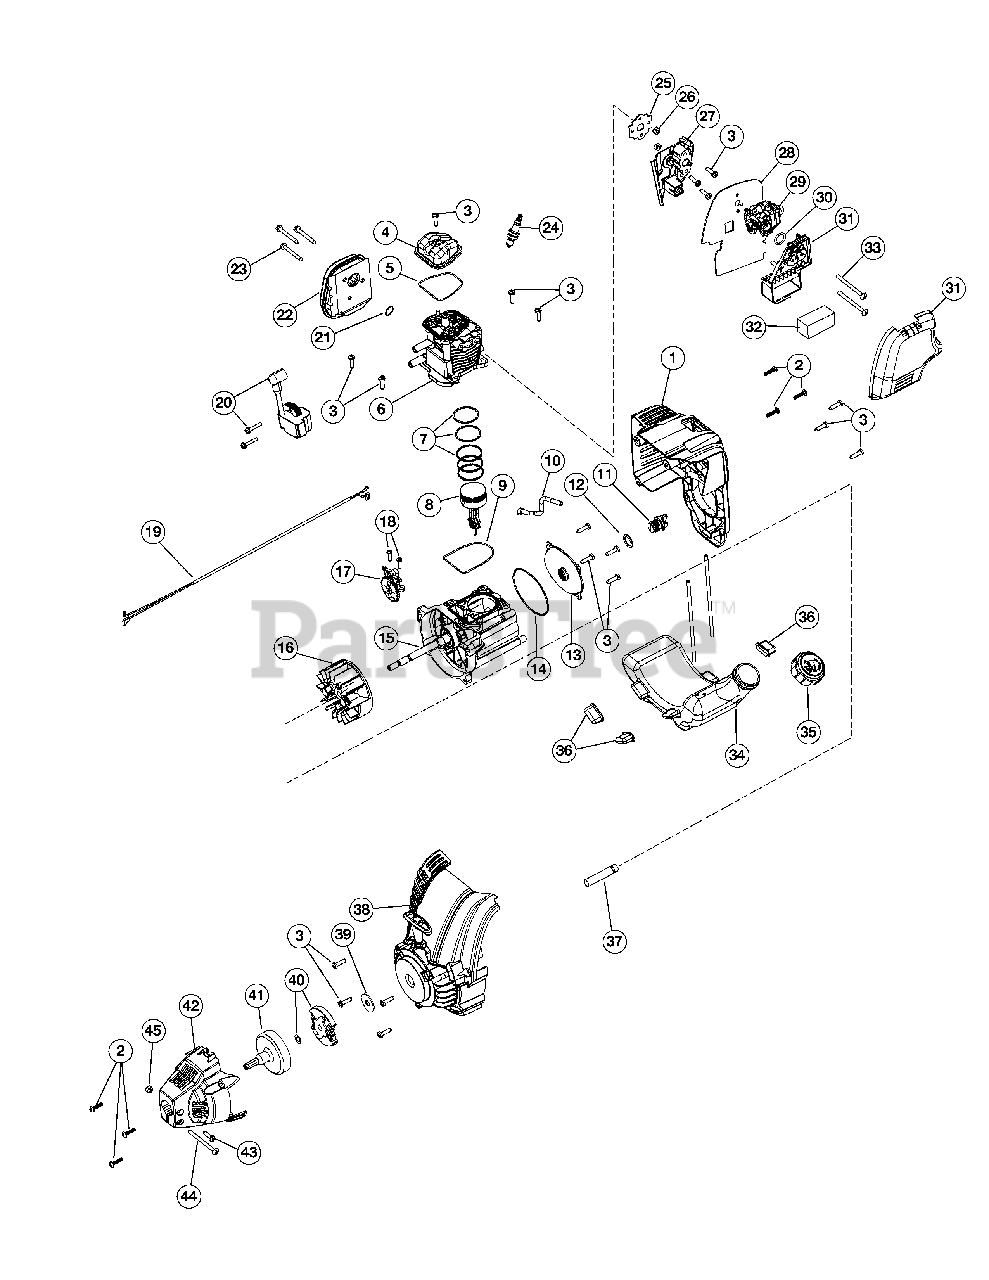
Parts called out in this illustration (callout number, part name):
1	Engine Cover Assembly
2	Cover Screw
3	Screw
4	Rocker Cover
5	Rocker Cover O-Ring
6	Cylinder Assembly
7	Piston Ring Assembly
8	Piston Assembly
9	Cylinder O-Ring
10	Breather Hose
11	Oil Plug
12	Oil Plug O-Ring
13	Crankcase Cover
14	Crankcase Cover O-ring
15	Crankcase Assembly
16	Flywheel Assembly
17	Cam Bracket Assembly
18	Cam Bracket Screw
19	Lead Wires
20	Module Assembly
21	Muffler Gasket
22	Muffler Assembly
23	Muffler Screw
24	Spark Plug
25	Insulator Gasket
26	Nut
27	Insulator
28	Carburetor Gasket
29	Carburetor w/Primer
31	Air Cleaner Cover Assembly
32	Air Filter
33	Screw
34	Fuel Tank Assembly w/Fuel Lines
35	Fuel Cap
36	Fuel Tank Pads
37	Spacer
38	Starter Housing Assembly
39	Washer
40	Clutch & Clutch Washer
41	Clutch Drum
42	Clutch Cover
43	Anti-Rotation Screw
44	Clamp Screw
45	Nut
